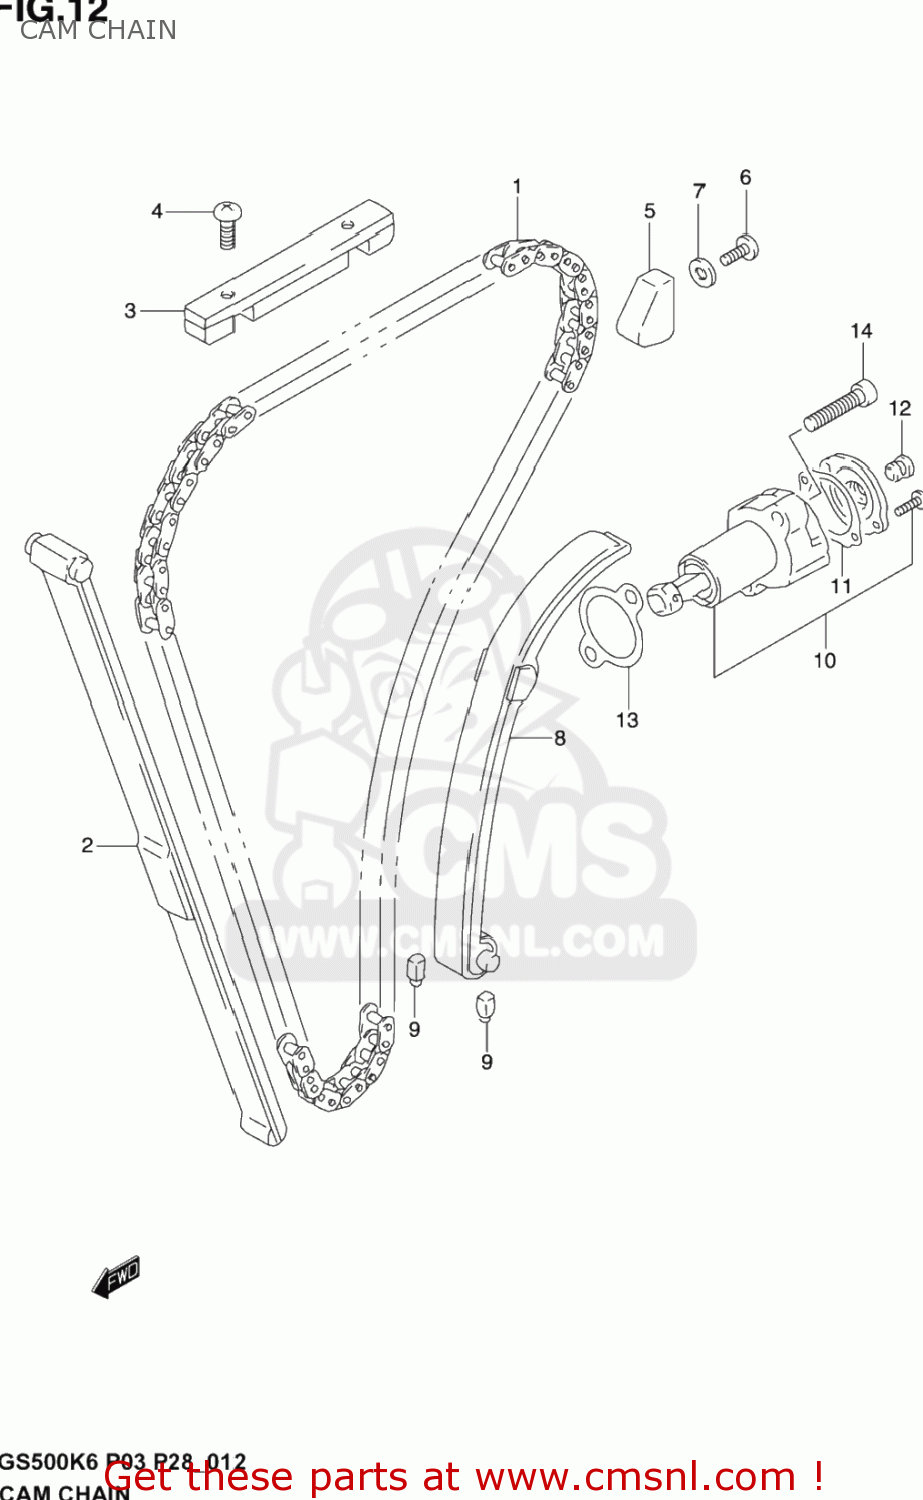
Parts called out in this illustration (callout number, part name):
1	CHAIN,CAMSHAFT DRIVE(120L)
2	GUIDE,CAM CHAIN NO.1
3	GUIDE,CAM CHAIN
4	SCREW
5	GUIDE,CAM CHAIN
6	BOLT
7	GASKET(5.8X13X1.2) (NAS)
8	TENSIONER,CAM CHAIN
9	CUSHION,CAM CHAIN TENSIONER
10	ADJUSTER ASSY,TENSIONER
11	GASKET,ADJUSTER CAP (NAS)
12	PLUG,ADJUSTER
13	GASKET,TENSIONER ADJUSTER (NAS)
14	BOLT,CL.COVER
